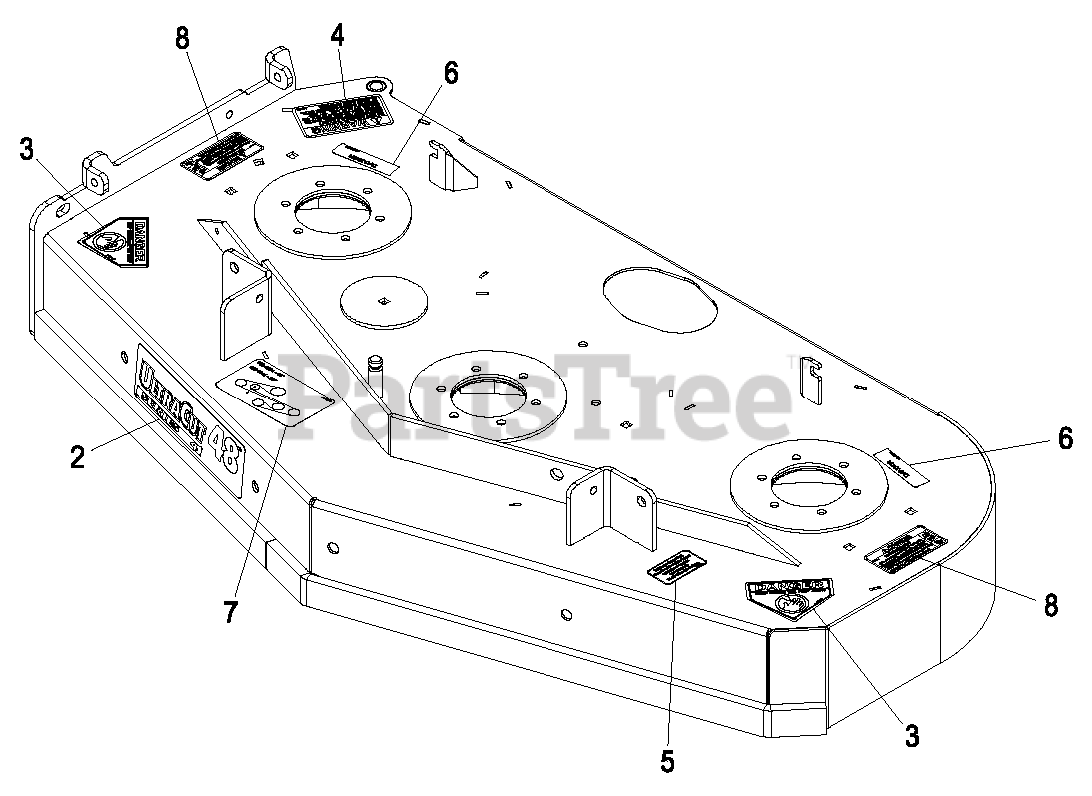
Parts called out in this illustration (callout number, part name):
2	DECAL,ULTRACUT 48 SERIES
3	DECAL-DANGER
4	DECAL-WARNING, DISCHARGE
5	DECAL,BOLT TORQUE
6	DECAL-COVER, MISSING
7	DECAL-BELT ROUTING
8	DECAL-ROTATING PARTS
